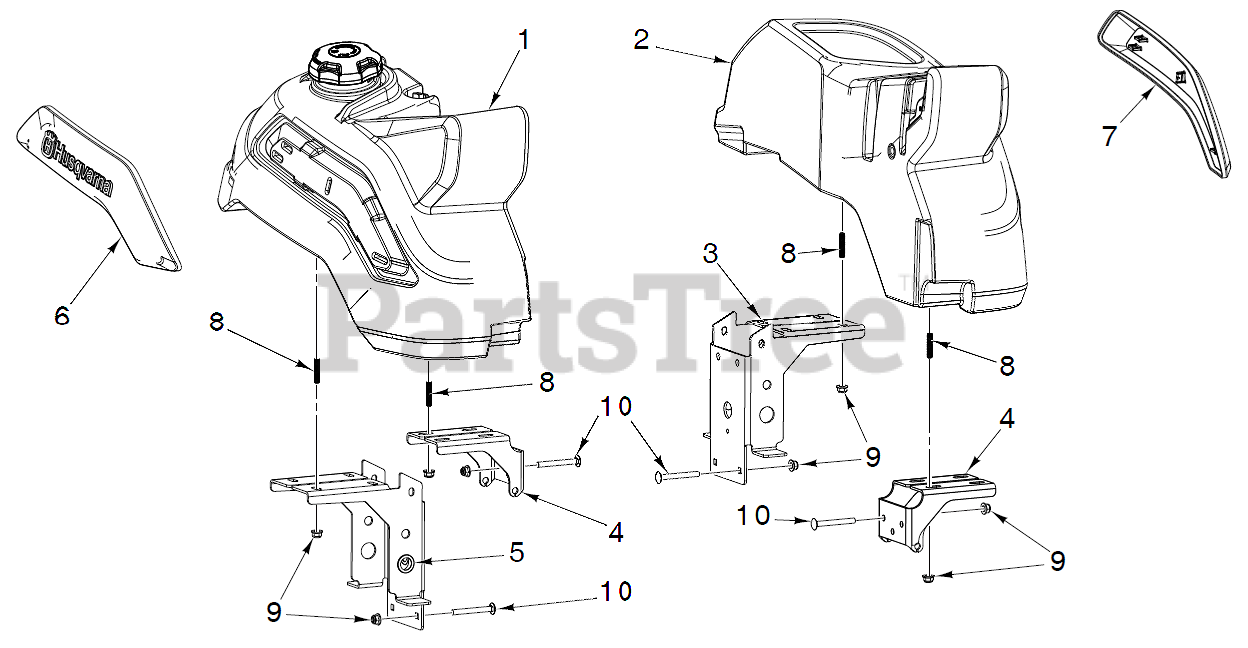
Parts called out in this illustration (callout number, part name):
1	Tanks
2	Consoles
3	Brackets
4	Brackets
5	Bushings
6	COVER.RH.FUEL.TANK/CONSOLE APP
7	COVER.LH.FUEL.TANK/CONSOLE APP
8	SCREW.5/16-18X1.25"THREADED
9	NUT HEXAGON FLANGE 5/16-18 ST
10	Bolt, Carriage 5/16-18 x 2 - 3/4
